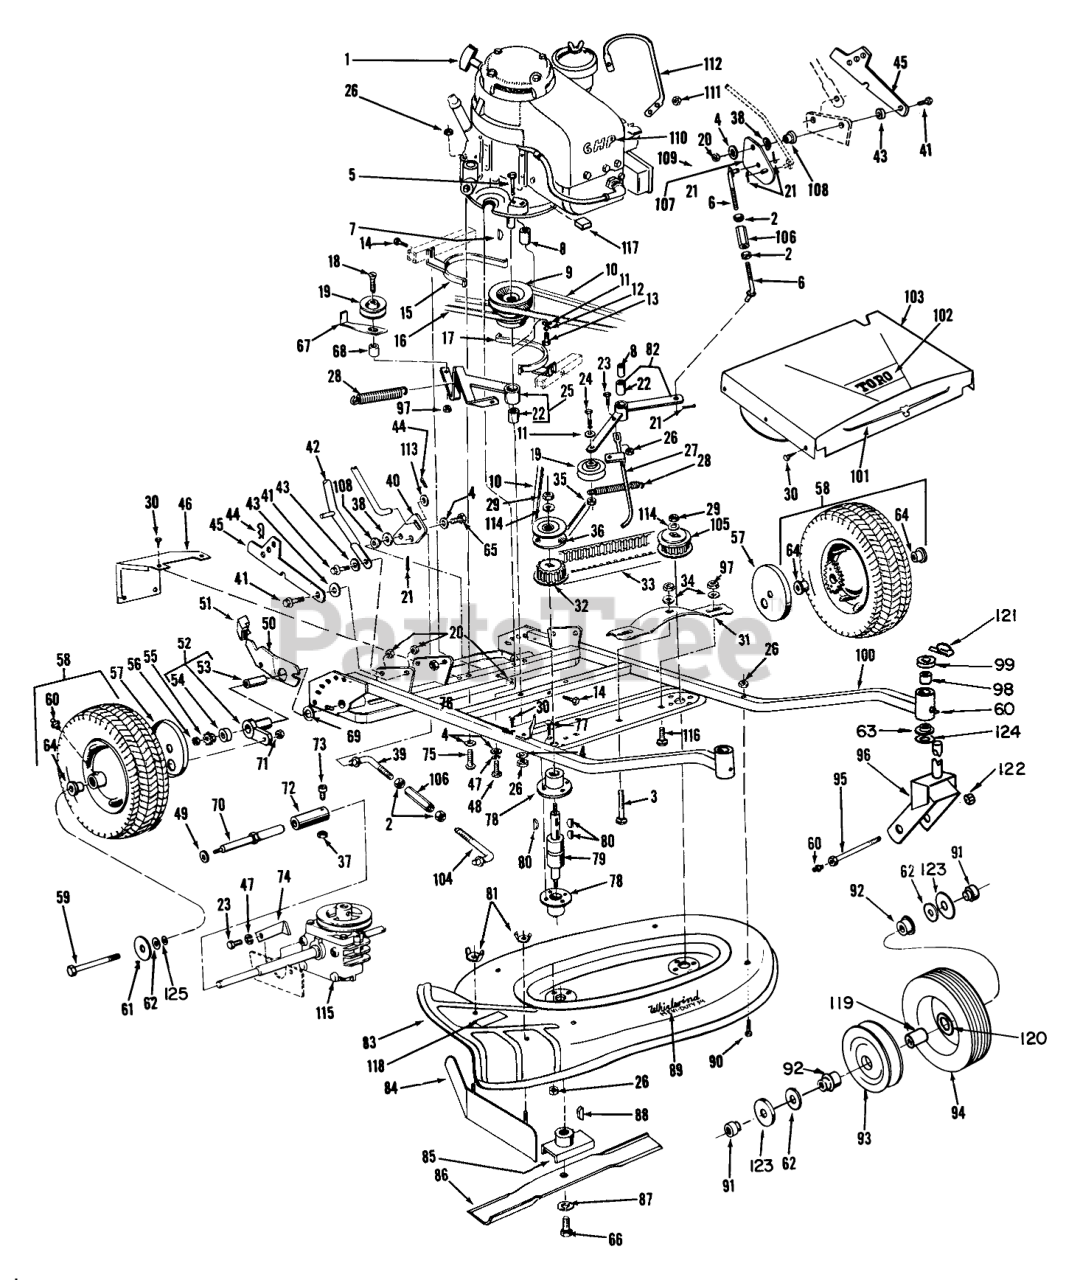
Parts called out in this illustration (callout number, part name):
1	Engine
2	NUT-HEX
3	SCREW-CARR
4	WASHER-PLAIN
5	SCREW-HH
6	TRACTION LINK
7	KEY-WOODRUFF
8	ENGINE PIVOT SPACER
9	Pulley
10	CUTTER BELT
11	WASHER-FLAT
12	WASHER-LOCK
13	SCREW-HH
14	SCREW-HH
15	Retainer, Belt
16	TRACTION BELT
17	Retainer, Belt
18	SCREW-HH
19	IDLER PULLEY R
20	NUT-LOCK, NI
21	PIN-COTTER
22	BUSHING
23	SCREW-HH
24	Screw
25	Arm & Bushing Assy.
26	NUT-LOCK, NI
27	Brake Arm
28	EXTENSION SPRING
29	NUT-LOCK, NI
30	10-16 X 3/8 THDG SCREW
31	Plate, Spreader
32	Pulley
34	WASHER-FLAT
35	NUT-HEX
36	Pulley
37	NUT-LOCK, NI
38	WASHER
39	TRACTION LINK
40	Bell Crank
41	SCREW-SHOULDER
42	Lower Handle Assy.
43	SPACER
44	PIN-COTTER
45	Latch
46	Rear Shroud
47	WASHER-LOCK
48	SCREW-HH
49	Washer
50	RH SPRING ARM ASM
50	LH SPRING ARM ASM
51	ARM KNOB
52	Pivot Arm
53	BUSHING
54	.375 RPP BALL BEARING
55	Pinion Kit
56	NUT-HJ
57	Wheel Cover
58	REAR WHEEL & TIRE ASM
59	SCREW-HH
60	FITTING-GREASE
61	SLINGER
62	Washer
63	FLANGE BUSHING
64	BEARING
65	Screw-HH
66	SPECIAL SCREW
68	Spacer
69	Washer
70	DRIVE SPINDLE
71	NUT-LOCK, NI
72	Clutch Assy.
73	DRIVE SCREW
74	Retainer
75	SCREW-HH
76	Belt Retainer
77	Bolt
78	Bearing Housing
79	Bearing, Spindle-Right
80	KEY-WOODRUFF
81	NUT-WING SPECL
82	Arm & Bushing Assy.
83	Housing
84	Leaf Mulcher
85	BLADE RETAINER WA
86	18 BLADE
87	WASHER-LOCK
89	Decal
91	CASTOR SPACER
92	BEARING-BALL
93	Wheel Disc (Incl. Ref. No. 92)
94	1.75-8 SEMIPNEU TIRE
95	AXLE BOLT
96	CASTOR FORK WA RO
97	NUT-LOCK, NI
98	7/8 ID X 1.128 X 7/8 LG BSHG
99	HT OF CUT SPACER
100	Frame
101	Decal
102	Decal
103	Shroud
105	Pulley
106	CONTROL ROD SLEEVE
107	Bellcrank
108	PIVOT
109	SCREW-HWH, THREAD CUT
110	Decal
111	NUT-LOCK
113	Spacer
114	WASHER-TOOTH, INTERNAL
115	Transmission Assembly
116	BOLT-CARR
117	Spacer
118	Decal
119	BRG SPACER
120	WASHER-SPECIAL
121	PIN-LYNCH
122	NUT-HEX
123	WASHER-FLAT
124	WASHER
125	O-RING
